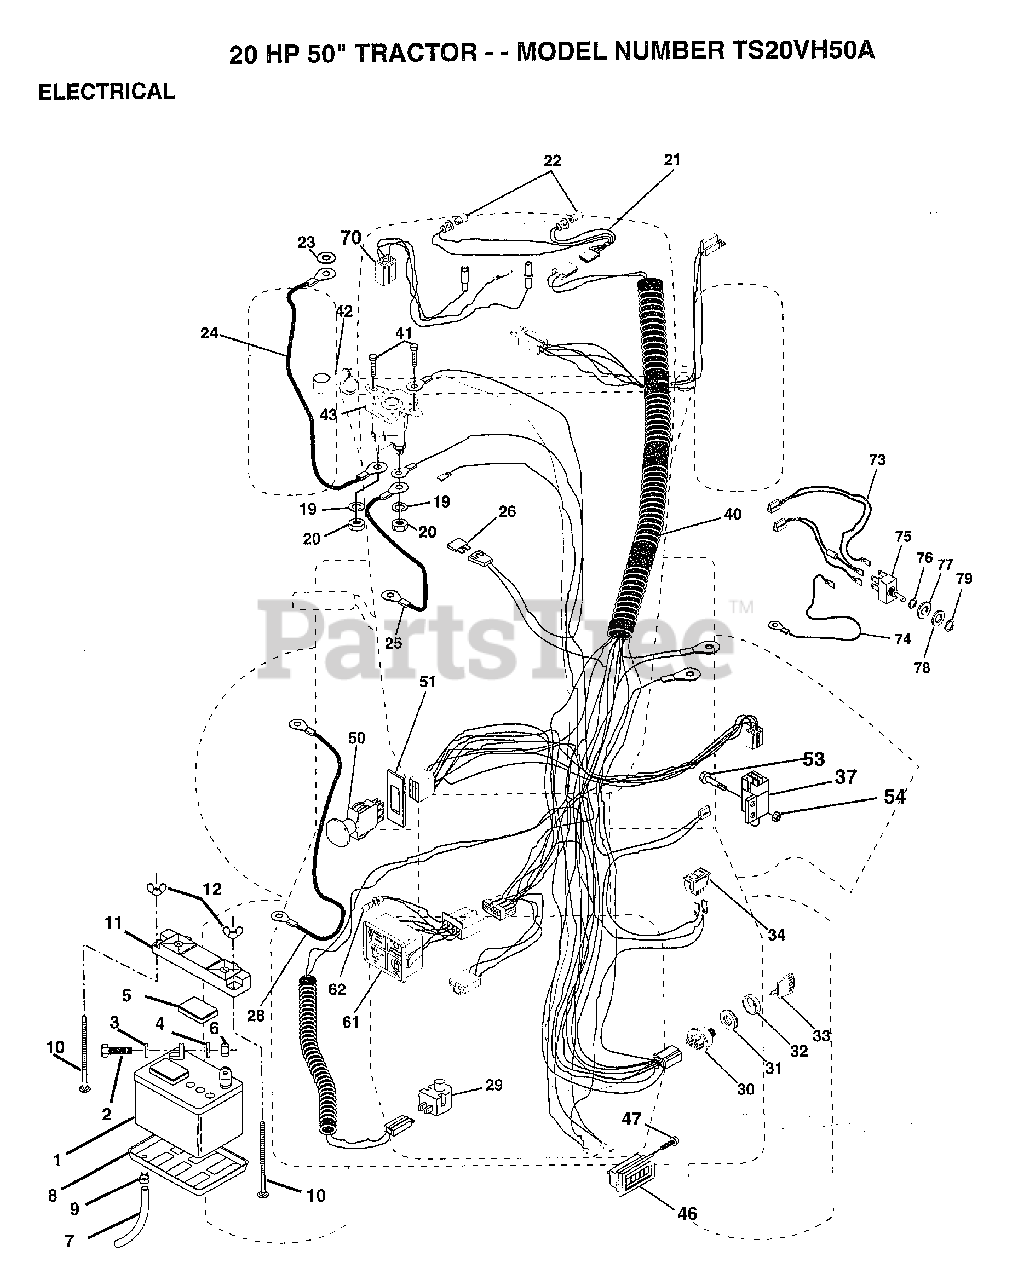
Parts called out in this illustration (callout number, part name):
2	BOLT LT
3	LOCKWASHER
4	WASHER
5	"CAP,BATTERY "
7	"DRAIN TU T, BATT"
8	"TRAY T, BATTERY"
9	HOSE CLAMP T
10	BOLT
20	NUT
22	HEADLAMP BULB
23	LOCKWASHER
24	CABLE-BATTERY T
25	CABLE-BATTERY T
26	FUSE HYT
28	CABLE T
29	SWITCH SEAT
32	COVER KEY SWITCH
33	KEY MLD GEN DELTA
34	SWITCH LT
37	SWITCH INTERLOCKT
40	HARNESS IGNITION
41	SCREW
46	HOUR METER T
47	SCREW
51	RING RETAIN PTO
53	SCREW
54	"NUT,KEPS"
61	LIGHT.PKG.ASM.
62	BULB LIGHT T
70	HARNESS.ENG.VANII
73	"HARNESS,WIRE"
74	WIRE LIFT SWI T
78	WASHER
79	NUT, SWITCH
